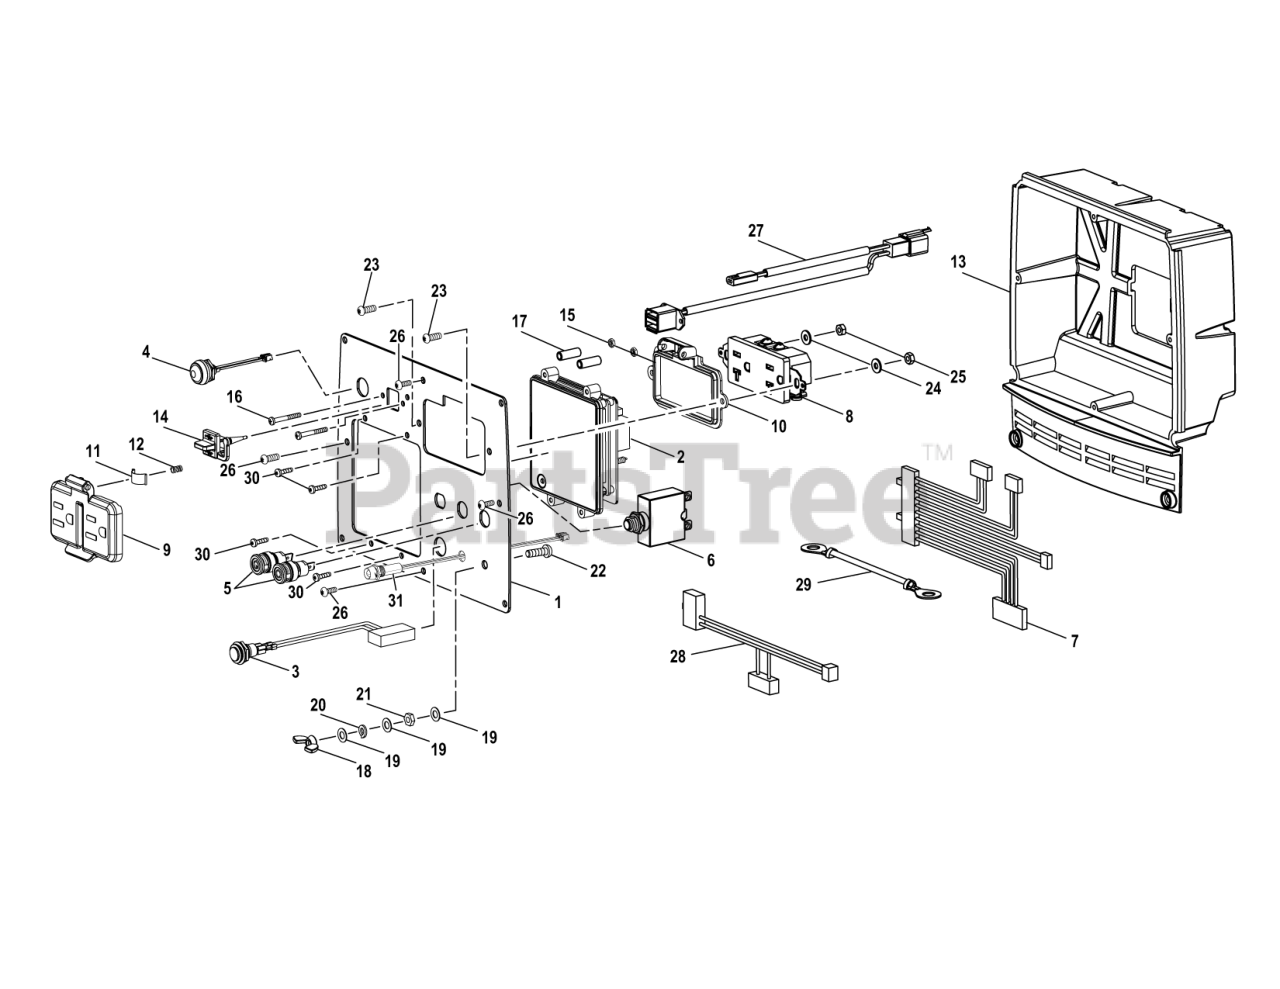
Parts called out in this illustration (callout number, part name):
1	FACEPLATE
2	ASSY., ECHO COMMAND DISPLAY
3	SWITCH, OVERLOAD REST
4	SWITCH, AUTO IDLE
5	CONNECTOR (BLACK)
6	BREAKER, CIRCUIT (20A)
7	HARNESS, GENCONTROL DISPLAY
8	OUTLET, 120V (20 AMP)
9	COVER, OUTLET
10	COVER, FIXED OUTLET
12	SPRING, COMPRESSION
13	HOUSING, ELECTRICAL PANEL
14	COVER, DUAL USB
18	NUT, WING
20	WASHER, LOCK
21	NUT, HEX
24	WASHER, FLAT
25	NUT, HEX
27	HARNESS, REGULATOR WIRE
28	ASSY., INTERNAL WIRE
29	WIRE, GROUND
31	INDICAOR, CO LED
